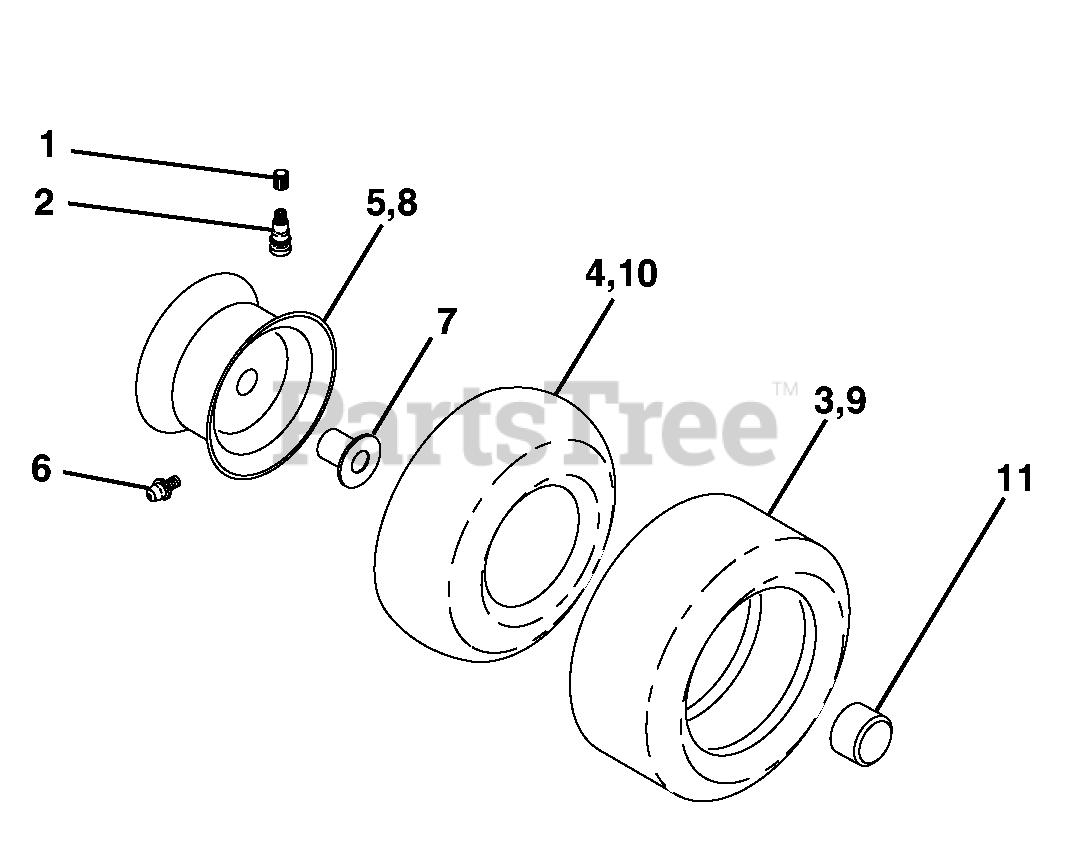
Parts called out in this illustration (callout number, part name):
1	Cap Valve Tire
2	Stem Valve
3	Tire F T 15 x 6 0 - 6 Service
4	Tube Front (Service Item Only)
5	Rim Asm 6" front Service
6	Fitting Grease (Front Wheel Only)
7	Bearing Flange (Front Wheel Only)
8	Rim Asm 8" rear Service
9	Tire R T
10	Tube Rear (Service Item Only)
11	Cap Axle Blk 1 50 x 1 00
